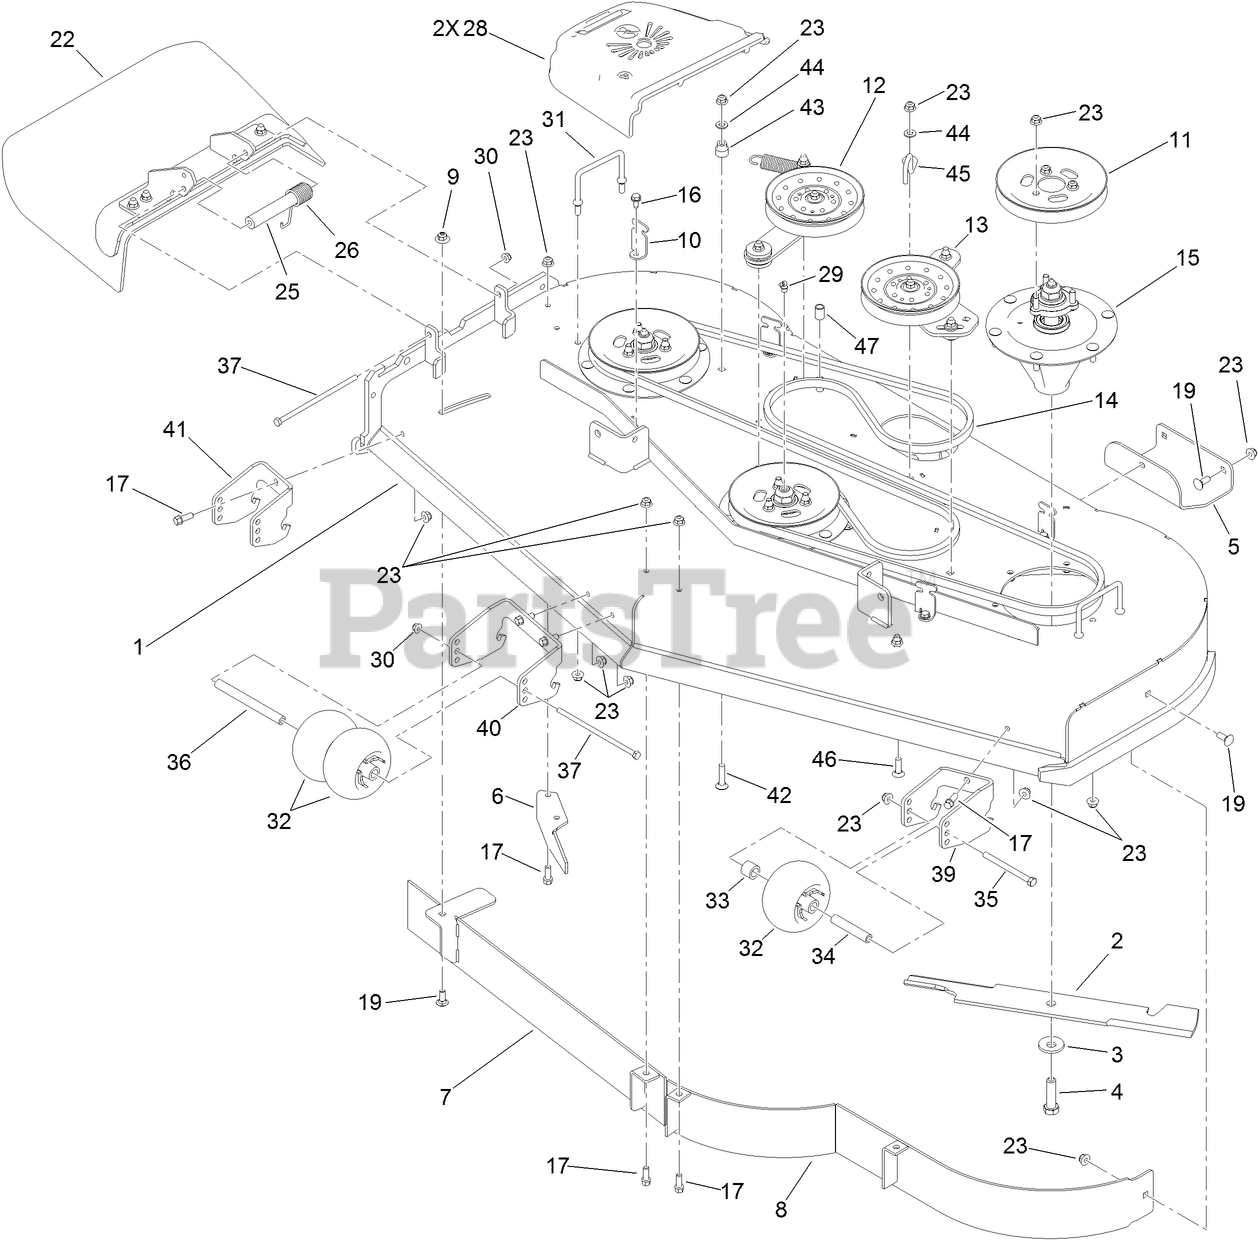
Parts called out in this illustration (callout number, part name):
1	DECK ASM
2	BLADE-HI FLOW
3	Washer-Blade Bolt, Heavy
4	SCREW-BLADE
6	BAFFLE-DISCHARGE
7	BAFFLE ASM
8	BAFFLE ASM
9	NUT-FLANGE, NI
10	BRACKET-COVER
11	PULLEY
12	RH IDLER ARM ASM
13	LH IDLER ARM ASM
14	BELT-V
15	SPINDLE ASM
16	SCREW-HWHTF
17	SCREW-HWH
19	BOLT-CARR
22	DEFLECTOR ASM
23	NUT-HF, NI
25	SPACER
26	SPRING-TORSION
28	COVER-BELT
29	FITTING-GREASE
30	NUT-HF, NI
31	WIREFORM-COVER
32	ROLLER-SCALP, ANTI
33	TUBE-SPACER
34	TUBE-SPANNER
35	SCREW-HH
36	SPACER-WHEEL
37	SCREW-HH
39	BRACKET-WHEEL, LH
40	BRACKET-WHEEL, CENTER
41	BRACKET-WHEEL, RH
42	SCREW-CARR
43	BUSHING-IDLER
44	WASHER-FLAT
45	GUIDE-BELT
46	SCREW-CARR
47	Bumper-Idler
